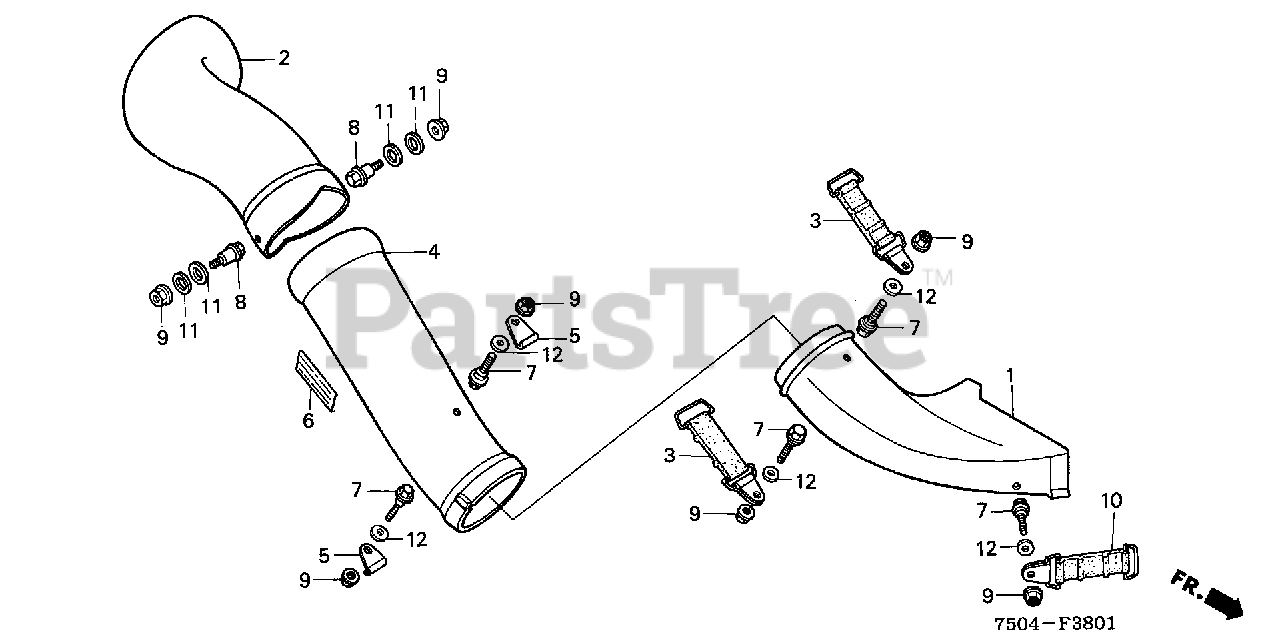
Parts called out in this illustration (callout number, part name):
1	CHUTE ASSY. (LOWER)
2	CHUTE (UPPER)
3	RUBBER ASSY., CHUTE TENSION
4	CHUTE ASSY., MIDDLE
5	HOOK, TENSION RUBBER
6	LABEL, CHUTE
7	BOLT, FLANGE (8X18)
8	SHOULDER CHUTE BOLT (UPPER)
9	NUT, STOP (6MM)
10	BAND ASSY., HOPPER TOP
11	WASHER, PLAIN (8MM)
12	WASHER, PLAIN (10MM)
